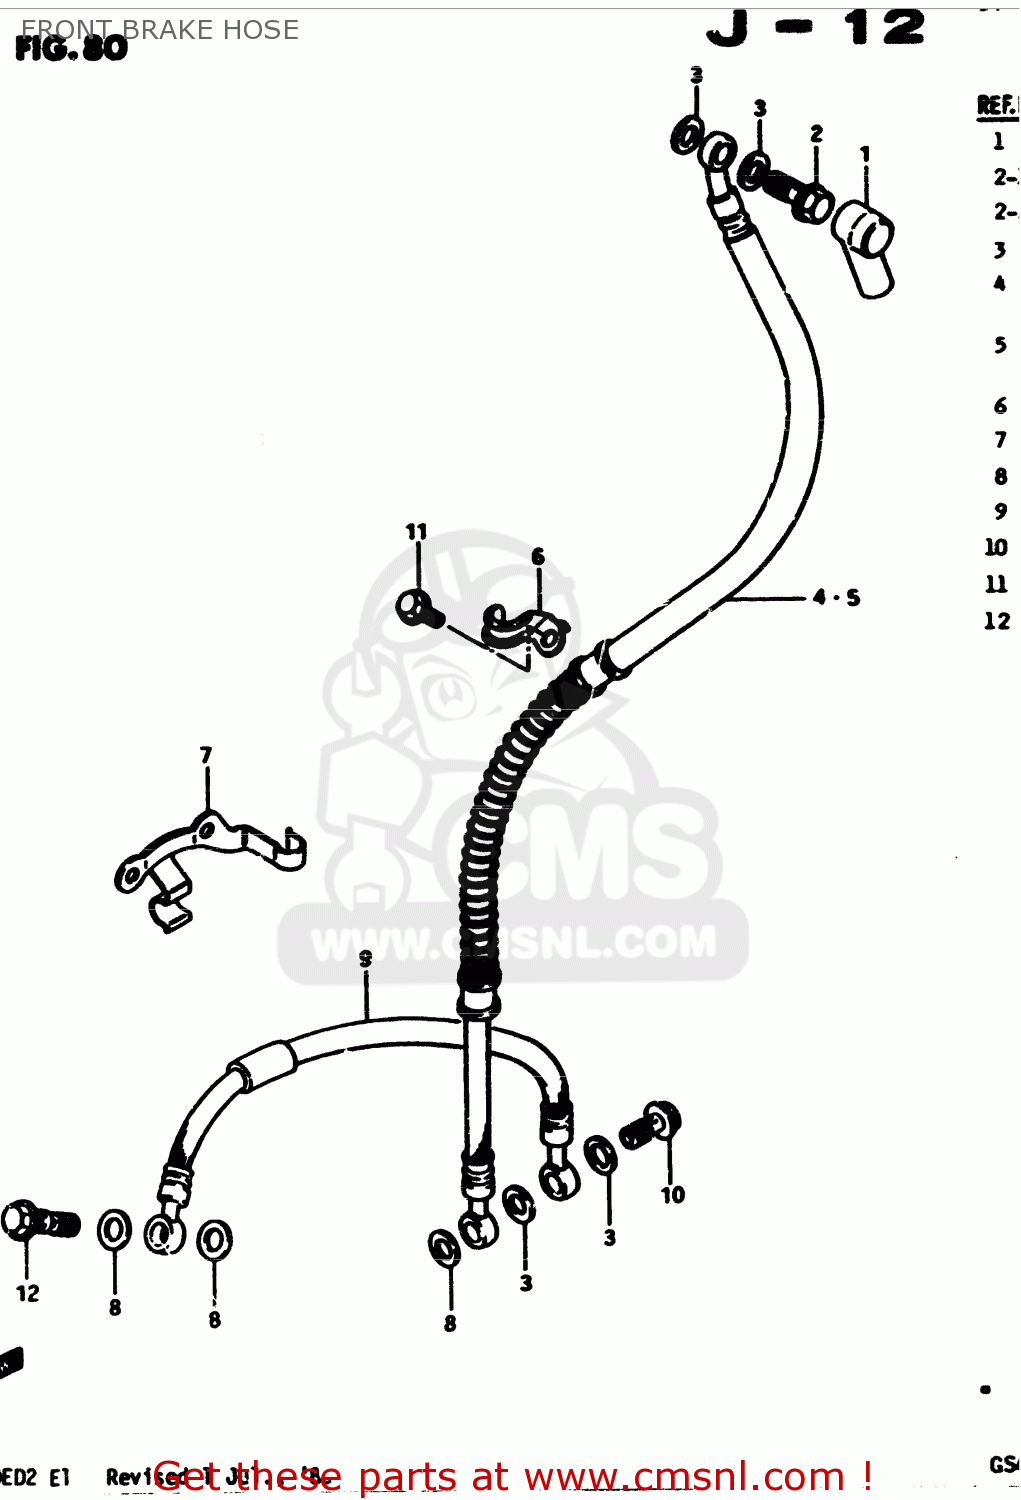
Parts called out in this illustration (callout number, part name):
1	BOOT,MASTER CYLINDER
2	BOLT,UNION
3	WASHER
4	HOSE,FR BRAKE
5	HOSE, BRAKE (FLAT HANDLEBAR)
6	GUIDE,BRAKE HOSE NO.3
7	CLAMP,BRAKE HOSE,LEFT
8	WASHER
9	HOSE,ANTI NOSE
10	BOLT,UNION
11	BOLT
12	BOLT UNION
